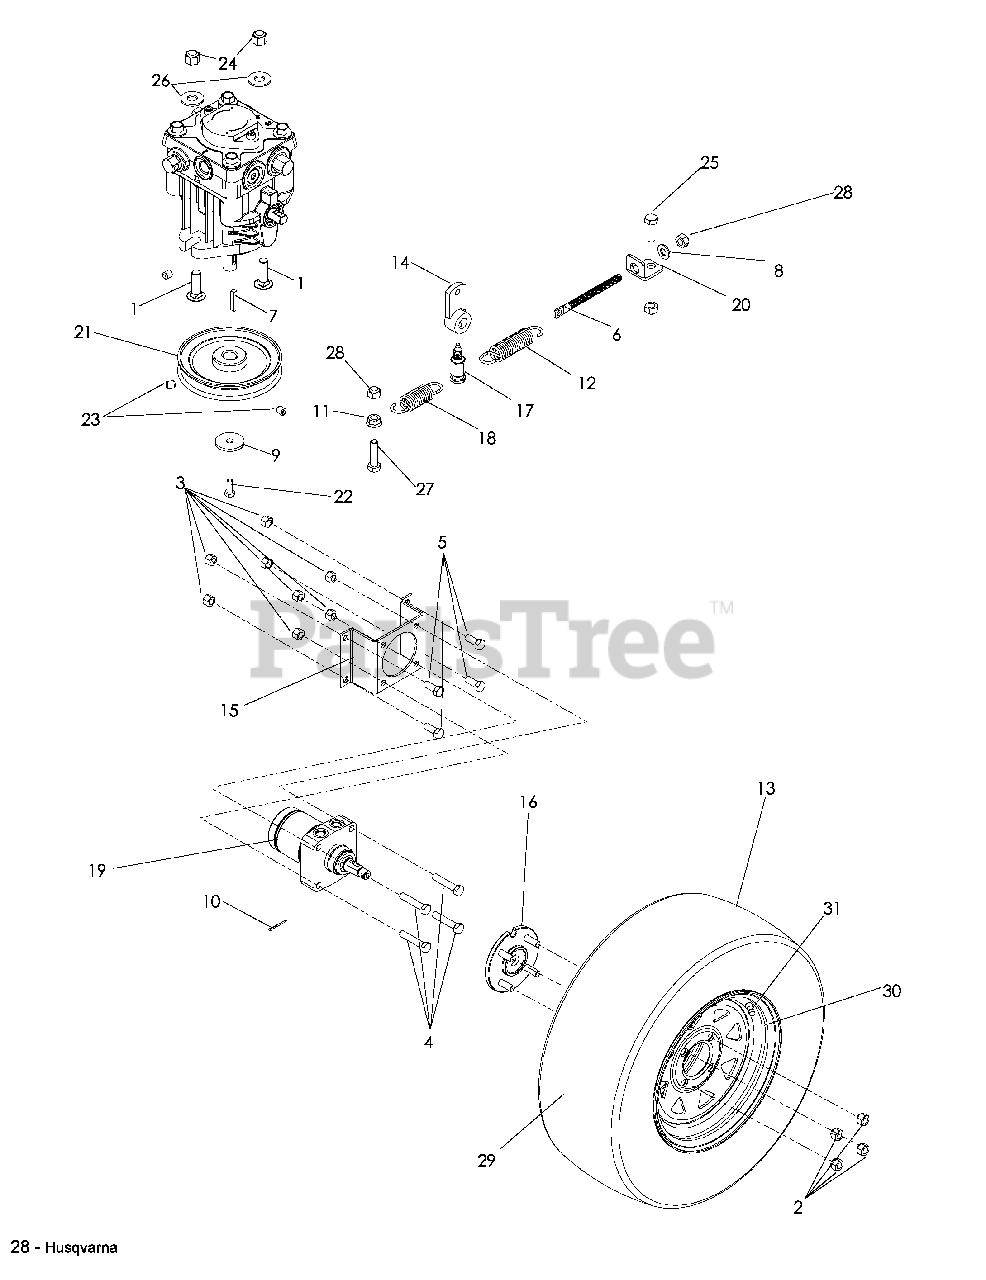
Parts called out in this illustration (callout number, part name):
1	RHSB 3/8-16 x 1¼
2	NUT ½-20 UNF LUG
3	NUT½-13 NYLOC
4	HHB ½-13 x 2½
5	HHB ½-13 x 1¼
7	KEY, 3/16 x 1
8	WASHER 5/16 TYPE A
9	WASHER 5/16 ID x 1/8 OD
10	COTTER PIN, 3/32 x 1 LG
11	NUT 5/16-18 HEX FLANGE
13	TIRE COMPLETE 23 x 8.5-12
14	CONTROL ARM, DRILLED
15	MOUNT, MOTOR
17	SCREW W/HEX HEAD SET
19	MOTOR, PARKER
20	SPRING MOUNT
22	BOLT M6 x 1 x 16MM
23	SCREW 5/16-18 x .38 SET
24	NUT 3/8-16 NYLOC
25	HHB 5/16-18 x 1
26	WASHER 3/8
27	HHB 5/16-18 x 1¼
28	NUT 5/16-18 NYLOC
29	TIRE
30	RIM, 12 x 7
31	VALVE STEM
